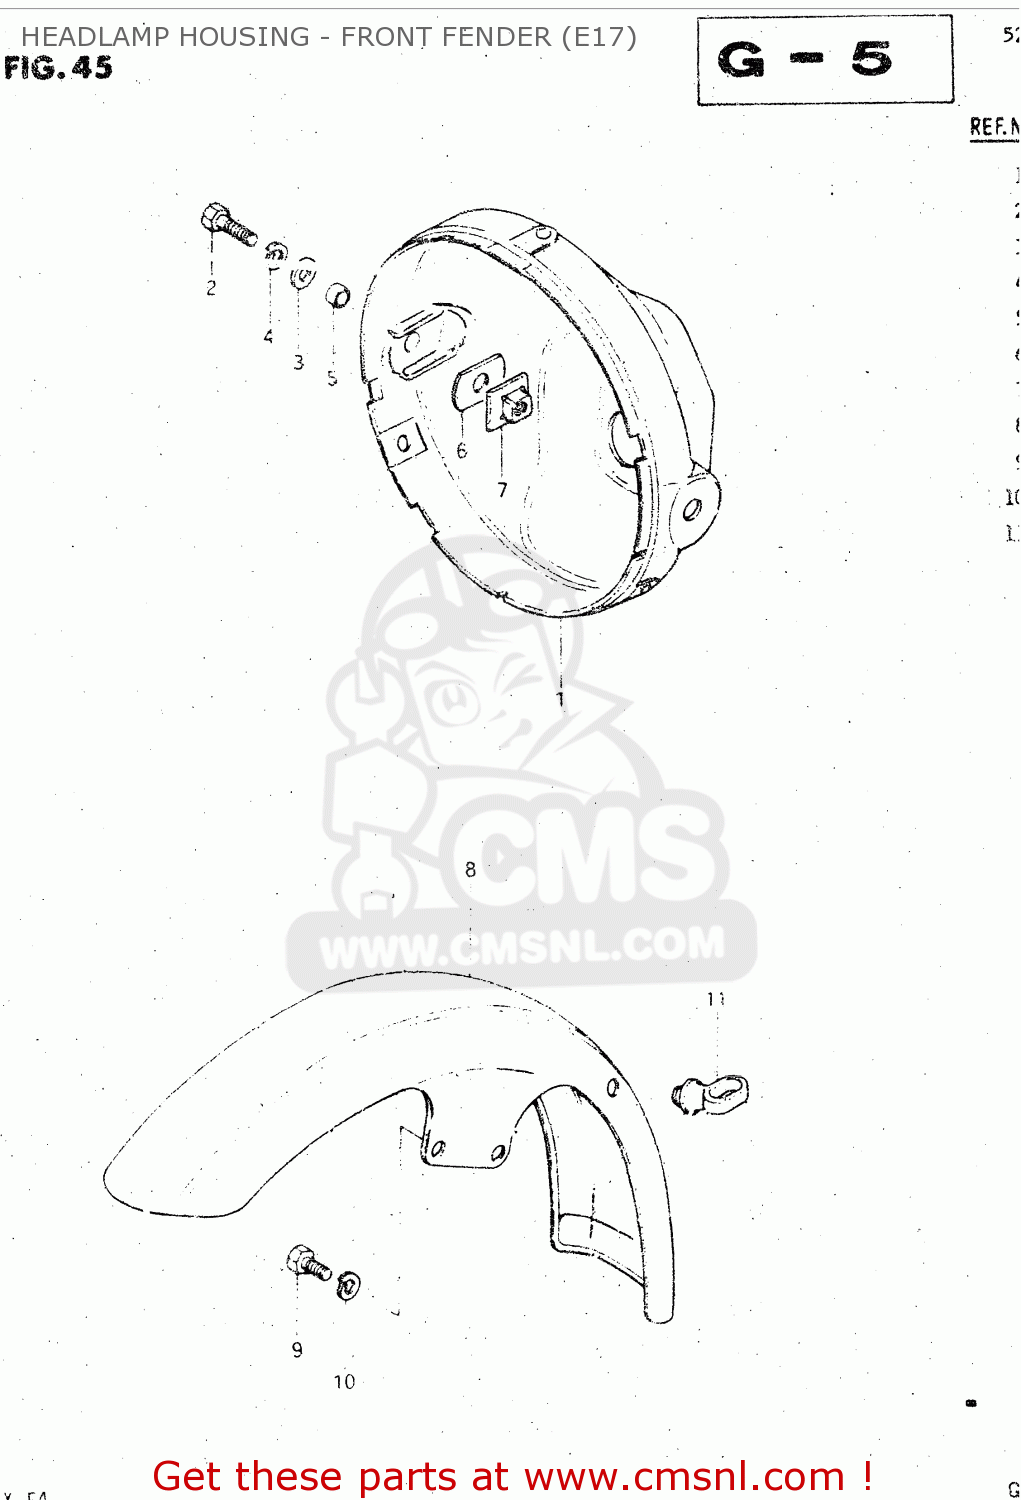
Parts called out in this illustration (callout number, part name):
1	HOUSING,HEADLAMP
2	BOLT
3	WASHER
4	LOCK WASHER
5	SPACER (8.8X12X7)
6	CUSHION
7	PLATE,HEADLAMP HOUSING
8	FENDER ASSY,FR
9	BOLT
10	LOCK WASHER
11	GUIDE,CABLE
